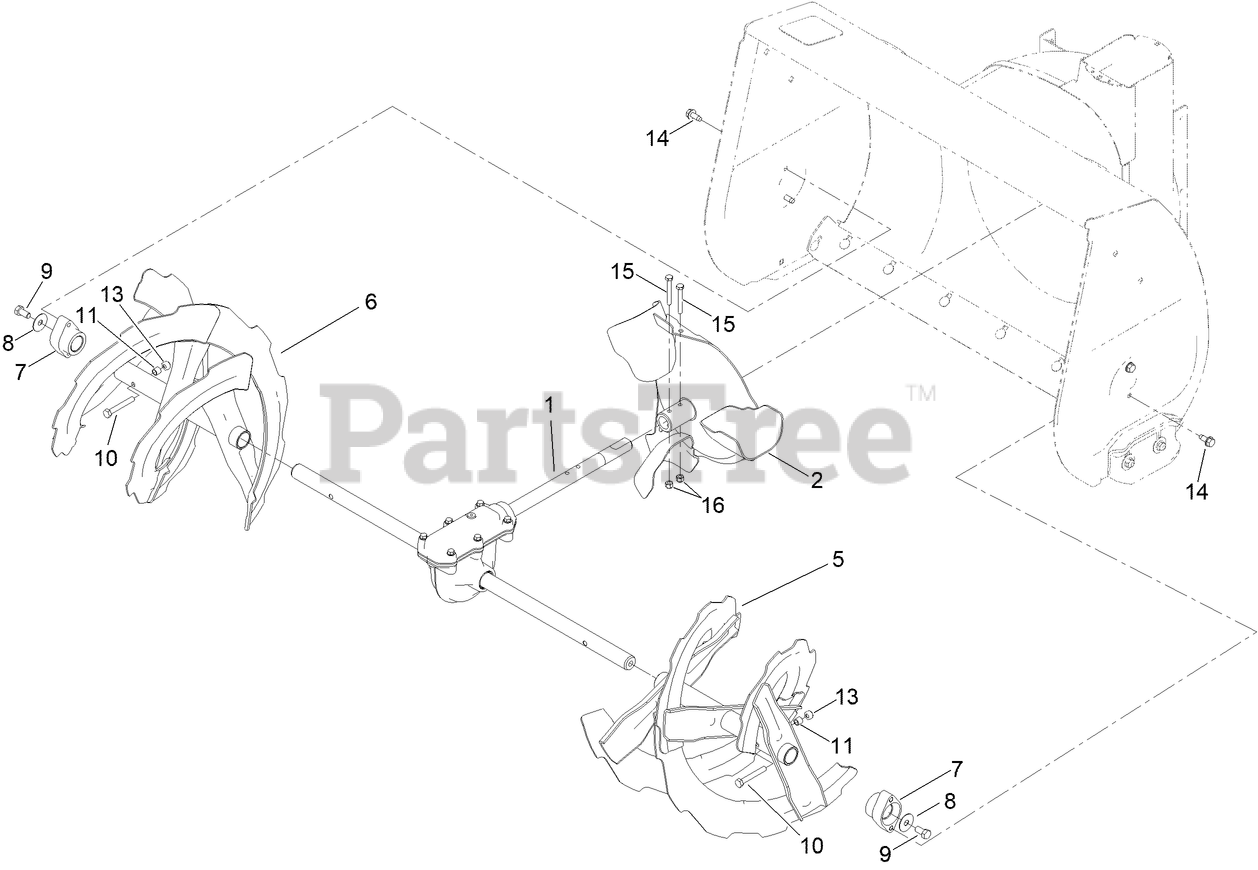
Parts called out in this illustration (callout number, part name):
1	AUGER GEARCASE ASM, 30 IN
2	IMPELLER
5	AUGER LH, 30" [BLACK]
6	AUGER RH, 30" [BLACK]
7	BEARING-AUGER
8	WASHER
9	SCREW-HH
10	SCREW-HH
11	SPACER-GROMMET
13	NUT-HEX
14	SCREW-HWHTF
15	SCREW-HH
16	NUT-HEX
